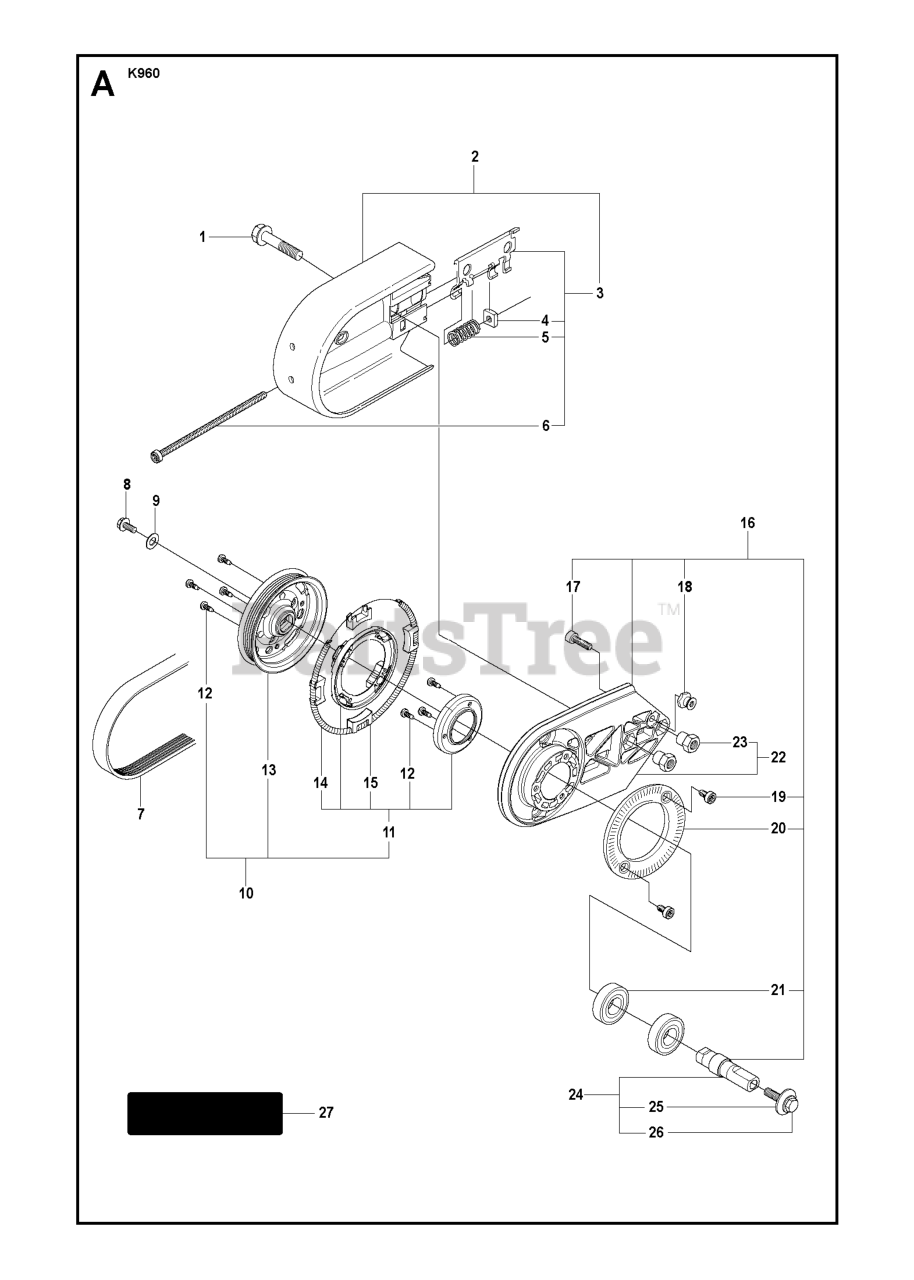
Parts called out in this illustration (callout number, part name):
2	BELT GUARD
7	BELT MICRO V 16"
7	BELT MICRO V 12-14"
10	PULLEY
11	CASSETTE, FRICTION RETARDER
13	PULLEY
14	DRAW SPRING
15	BRAKE SHOE
16	BEARING HOUSING
17	SCREW ITXSCM
21	BALL BEARING
22	HOUSING
24	SHAFT
25	WASHER
